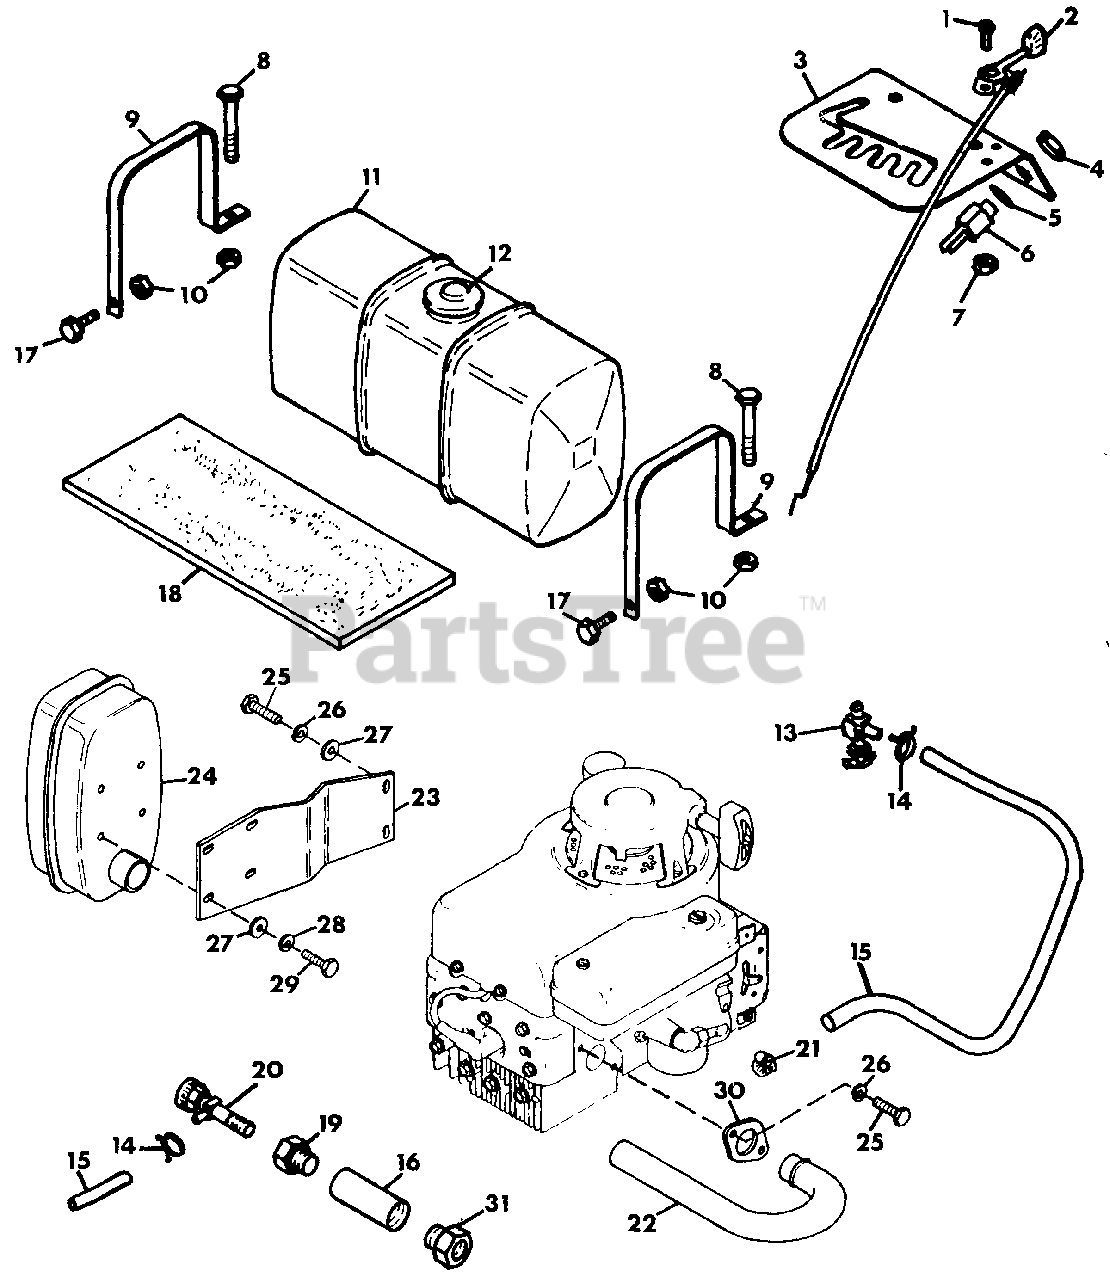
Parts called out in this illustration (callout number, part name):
1	SCREW, MACH. 10-24X.50
2	LEVER, THROTTLE-CHOKE
3	PLATE, INSTRUCTION
4	NUT, JAM 5/8-32
5	WASHER, LOCK 5/8
6	SWITCH, KEY
7	NUT, LOCK 10-24
8	BOLT, HEX 1/4-20X1.75
9	STRAP, FUEL TANK
10	NUT, LOCK 1/4-20
11	TANK, FUEL (12 QTS.)
12	CAP, FUEL TANK
13	VALVE AND STRAINER
14	CLAMP, FUEL HOSE
15	HOSE, FUEL
16	COUPLING, PIPE 3/8 NPT
17	BOLT, HEX 1/4-20X.625
18	PAD, FUEL TANK
19	ADAPTOR, OIL DRAIN
20	COCK, OIL DRAIN
21	CLAMP, HOSE
22	TUBE, EXHAUST
23	PLATE, EXHAUST
24	MUFFLER, 11 H.P. B & S
25	BOLT, HEX 5/16-18X.75
26	WASHER, LOCK 5/16 REG.
27	WASHER, FLAT .344X.688X.065
28	WASHER, LOCK 1/4 REG.
29	BOLT, HEX 1/4-20X.75
30	FLANGE, MUFFLER
